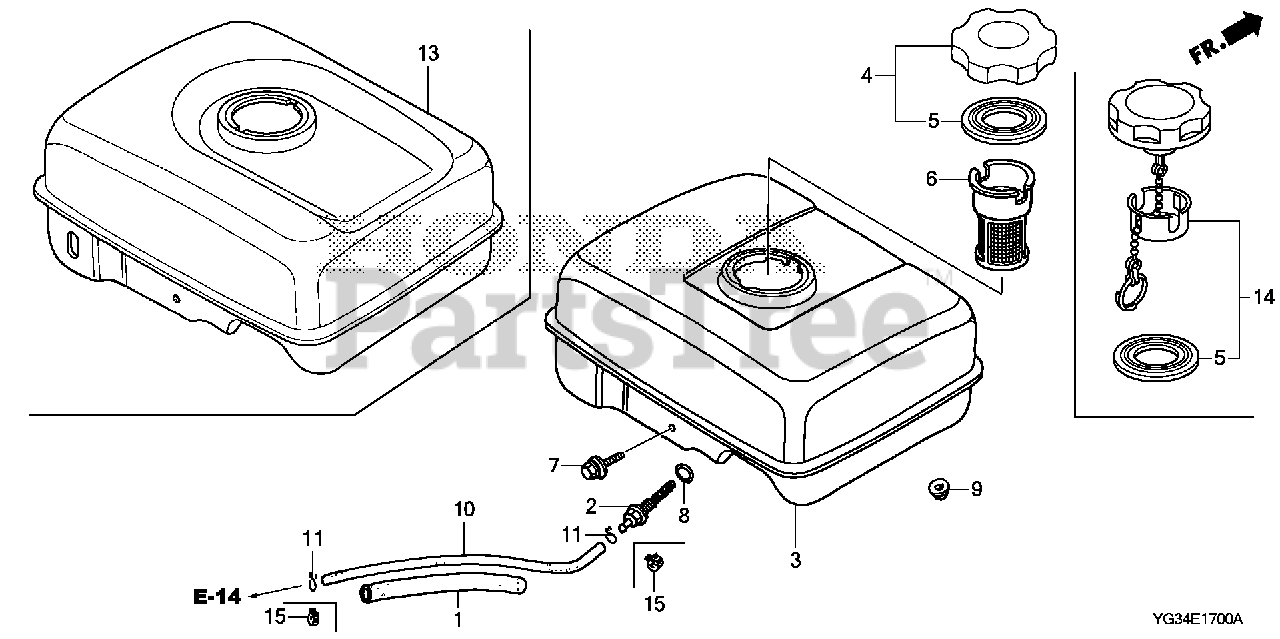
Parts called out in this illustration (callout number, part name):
1	RUBBER, SUPPORTER (107MM)
2	JOINT, FUEL TANK
5	GASKET, FUEL FILLER CAP (39X62X3) (TOUYOUSYA)
5	GASKET, FUEL FILLER CAP
6	FILTER, FUEL
7	BOLT, FLANGE (6X29)
8	O-RING (14MM) (ARAI) Use up to Engine SN 2949254.
9	NUT, FLANGE (6MM)
10	TUBE, FUEL (4.5X140) (FKM)
10	TUBE, FUEL (4.5X140)
13	TANK, FUEL *R280* (GAUGELESS) (POWER RED)
14	CAP, FUEL FILLER
15	CLIP, TUBE (D8)
